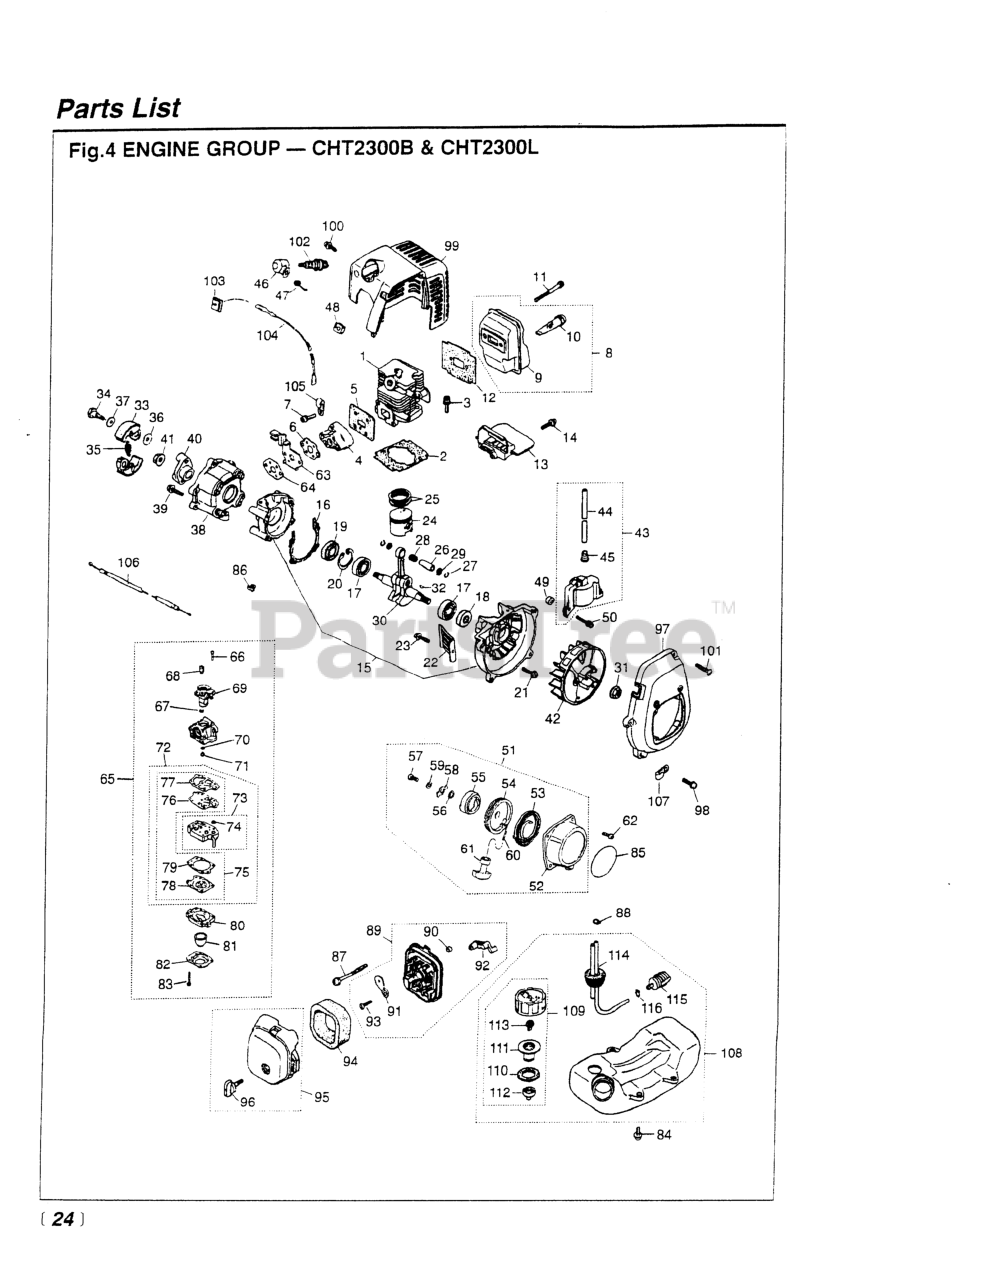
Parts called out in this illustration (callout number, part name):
1	CYLINDER
2	GASKET, BASE (RPLS -12212)
3	BOLT, M5 X 22
4	INSULATOR (REPLACES -13162)
5	GASKET (RPLS -13120)
6	GASKET (REPLACES -13130)
7	SCREW, M5X20 (RPLS.1400-75510)
8	MUFFLER ASSEMBLY
10	ARRESTER (RPLS 5850-15140)
11	BOLT, M5 x 50
12	GASKET, MUFFLER
14	SCREW, M4 X 16
15	CRANKCASE COMP.
16	GASKET (RPLS -21140)
17	BEARING
18	SEAL, OIL (RPLS 1100-21210)
19	SEAL, OIL (RPLS 1140-21220)
20	RING, SNAP, M28 x 1.2
21	BOLT, M5 X 30
23	SCREW,M5 X 14 (RPLS 1400-15510
24	PISTON (REPLACES 1140-41110)
25	RING, PISTON (RPLS 1850-41210)
26	PIN, PISTON 5x8x26
27	RING, SNAP (RPLS 1101-41320)
28	BEARING (RPLS 1140-41330)
29	WASHER
30	CRANKSHAFT (RPLS -42000)
32	KEY
33	SHOE (RPLS 1100-51114)
34	BOLT
35	SPRING
36	WASHER, FLAT (USE 182303)
38	CASE, CLUTCH
39	SCREW
40	PLATE, CLUTCH
43	COIL
45	CAP
46	CAP
47	SPRING
48	GROMMET
49	SPACER (RPLS -71260)
50	BOLT
52	CASE, RECOIL
53	SPRING
54	REEL (USE-75131)
55	5990-75141 (RPLS. 1861-75141)
56	SPRING (REPLACES -75150)
58	RETAINER
59	WASHER
60	ROPE
61	KNOB (REPLACES-75180)
62	SCREW, M4 x 12
63	BRACKET
64	GASKET (REPLACES -13130)
65	CARBURETOR
67	RING
68	SWIVEL
69	VALVE ASSY
70	RING, O
73	BODY, PUMP
74	SCREEN
76	DIAPHRAGM, PUMP
77	GASKET, PUMP
78	DIAPHRAGM
79	GASKET, DIAPHRAGM
80	BODY, PURGE
81	PUMP, PRIMING
82	COVER, PUMP
83	SCREW
84	SCREW
86	CAP, CABLE END
87	SCREW, M5 x 60
88	CLIP
89	BODY-A (RPLS -82101)
90	SLEEVE
91	PLATE, CHOKE (RPLS-82130)
92	LEVER, CHOKE
93	SCREW (REPLACES 50030272)
94	ELEMENT
95	COVER ASSY (RPLS -82202)
96	KNOB (RPLS -82220)
97	COVER, FAN
98	SCREW, M5X20 (RPLS.1400-75510)
99	ENGINE COVER (RPLS-32100)
100	SCREW, M5 x 12
101	SCREW, HOUSING
104	CORD
105	CLAMP
106	CABLE
107	CLAMP
108	5607-85002 (RPLS. 5601-85001)
109	CAP ASSY (RPLS. 5601-85201)
110	PACKING
111	HOLDER - A (RPLS 5601-85230)
112	FILTER
113	STOPPER
114	PIPE COMPLETE
115	FILTER (RPLS 1850-85300)
116	CLIP (REPLACES 2841-31280)
NI	CLIP
